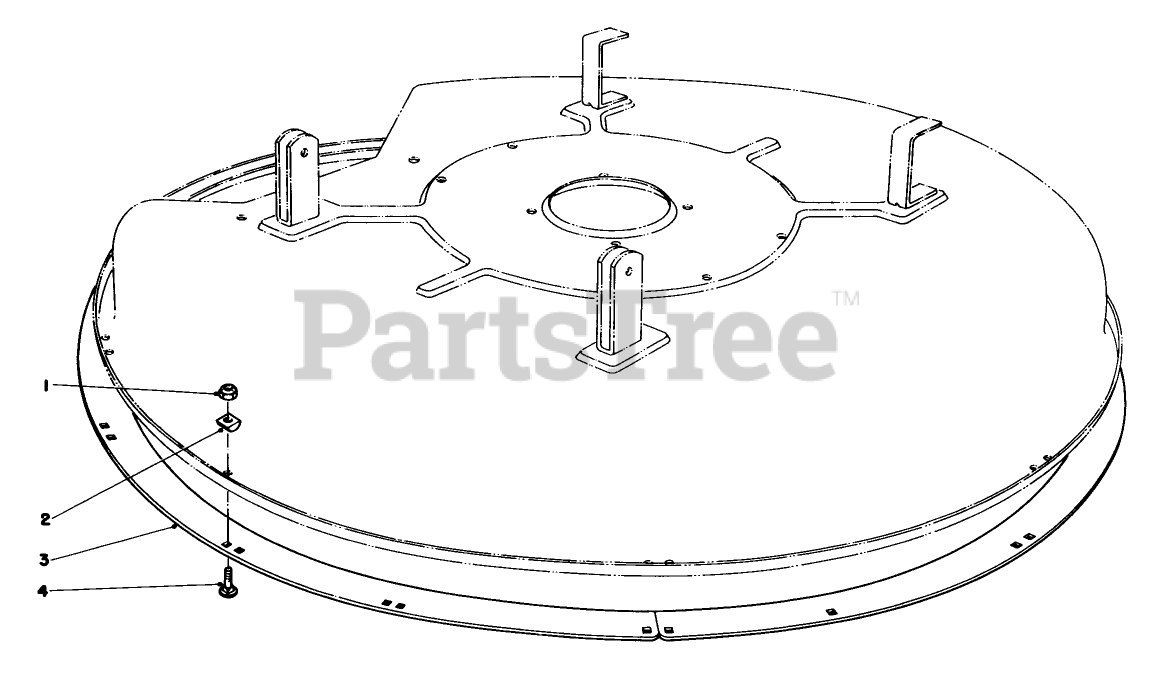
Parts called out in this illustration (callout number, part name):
1	NUT-LOCK, NI
3	DECK RING *B
4	BOLT-CARR
